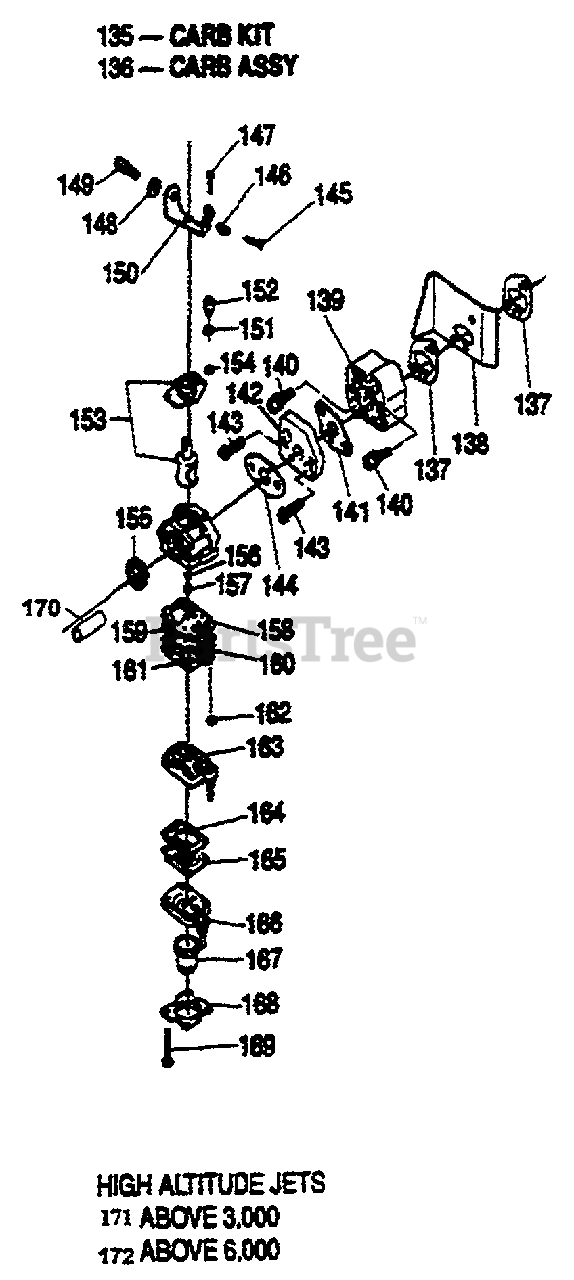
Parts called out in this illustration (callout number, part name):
136	CARB ASSY
137	GASKET, INSULATOR
139	INSULATOR
140	SCREW & WASHER
141	GASKET, CARB.
144	CASKET, CARB.
145	SCREW, IDLE
146	SPRING, IDLE
148	NUT, CABLE ADJ.
149	ADJUSTER, CABLE
153	VALUE, THROTTLE
154	RING, SWIVEL
158	GASKET, PUMP
159	DIAPHRAGM
162	SCREEN, INLET
163	BODY ASSY.
164	GASKET, DIAPH.
165	DIAPHRAGM
166	BODY, PUMP
167	PUMP, PIMER
168	COVER, PRIMER
169	SCREW, COVER
171	JET HIGH ALT.
172	JET HIGH ALT.
